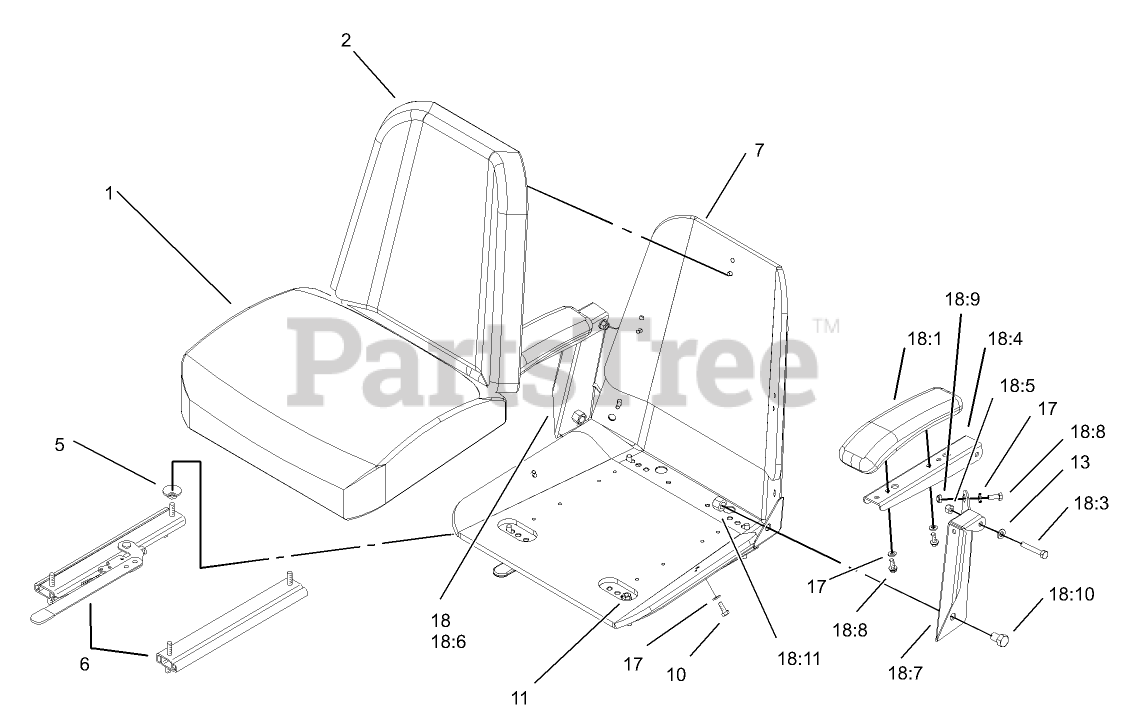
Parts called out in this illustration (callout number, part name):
1	CUSHION-SEAT, BOTTOM
2	CUSHION-SEAT, BACK
5	SPACER-TRACK
6	TRACK-SEAT
7	FRAME-SEAT
10	SCREW-HH
11	NUT-HF
13	WASHER-PLAIN
17	WASHER-FLAT
18	ARMREST KIT
18:1	CUSHION-ARMREST
18:3	SCREW-HH
18:4	CHANNEL-ARMREST
18:5	NUT-HEX, SIDE DEFORM
18:6	Bracket-Armrest, RH
18:7	Bracket-Armrest, LH
18:8	SCREW-HH
18:9	NUT-LOCK, NI
18:10	SCREW-HH
18:11	NUT-HEX
